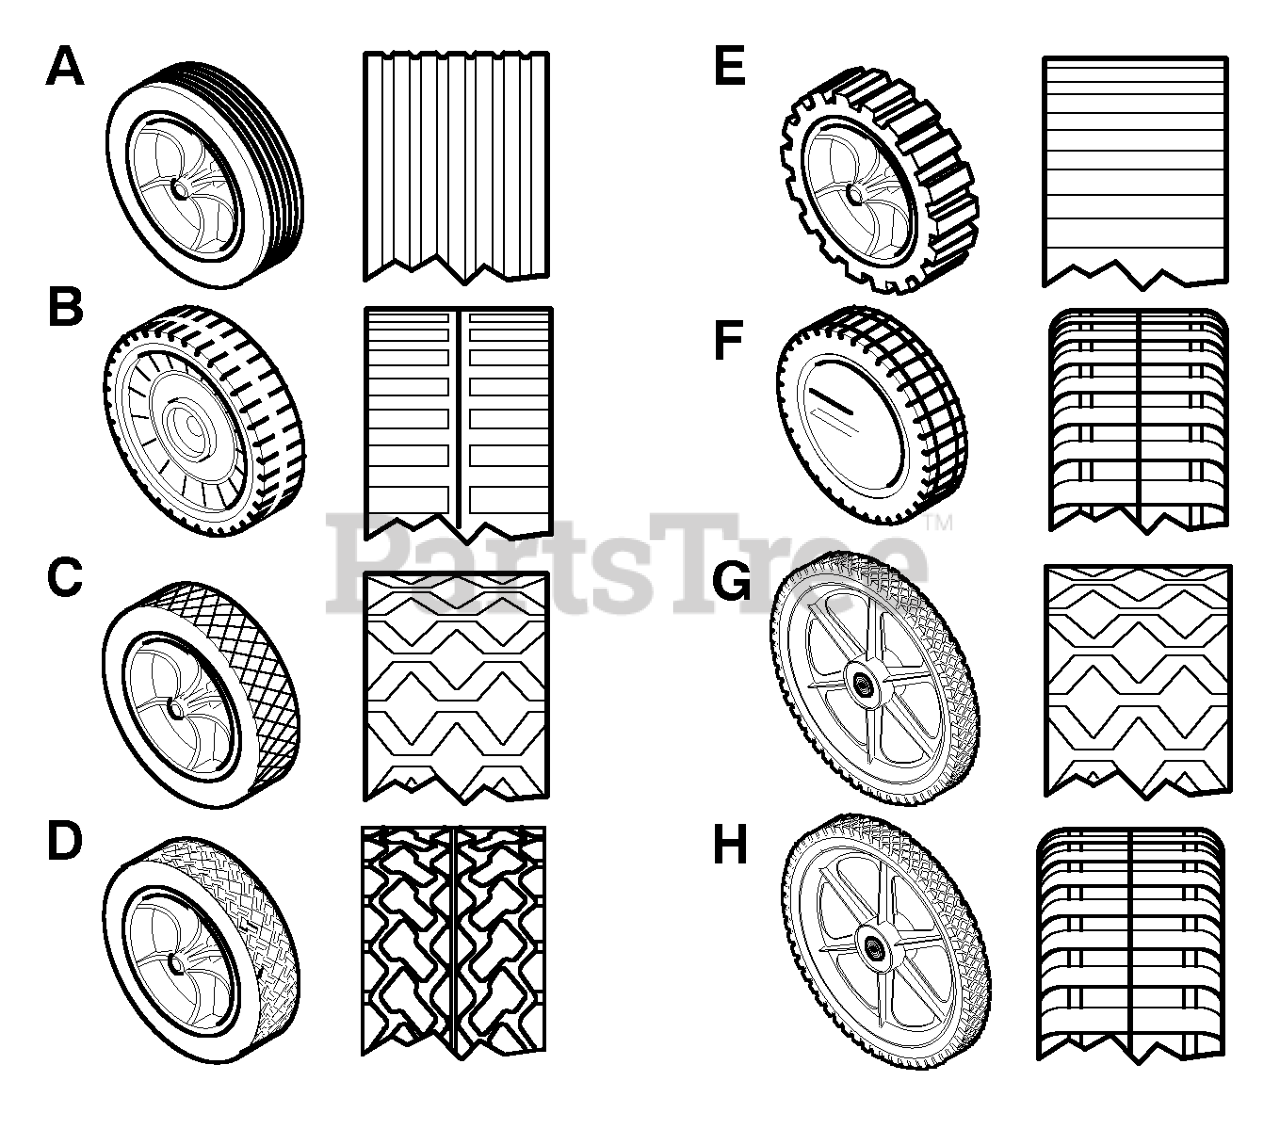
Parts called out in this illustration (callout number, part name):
A	WHEEL & TIRE ASSEMBLY, Light Gray, 8"
A	8-inch Plastic, Dark Gray
A	8-inch Metal, White
B	7-inch Plastic, White
B	7-inch Plastic, Light Gray
B	7-inch Plastic, Dark Gray
C	6-inch Plastic, White
C	7-inch Plastic, White
C	7-inch Plastic, Light Gray
C	7-inch Plastic, Dark Gray
C	8-inch Plastic, White
C	8-inch Plastic, Light Gray
C	8-inch Plastic, Dark Gray
C	8-inch Metal, White
D	7-inch Plastic, White
D	WHEEL & TIRE ASSEMBLY, White, 8"
D	8-inch Plastic, Light Gray
D	8-inch Plastic, Dark Gray
E	WHEEL & TIRE ASSEMBLY, White, 8"
E	8-inch Plastic, Dark Gray
E	8-inch Metal, White
F	WHEEL & TIRE ASSEMBLY, White, 8"
F	8-inch Plastic, Light Gray
F	8-inch Plastic, Dark Gray
F	8-inch Ball Bearing, Light Gray
F	8-inch Ball Bearing, Dark Gray
G	14-inch, White
G	14-inch, Light Gray
G	14-inch, Dark Gray
G	WHEEL & TIRE ASSEMBLY, White, 14"
G	14-in, Ball Bearing, Light Gray
G	14-in, Ball Bearing, Dark Gray
H	14-inch, White
H	14-inch, Light Gray
H	14-inch, Dark Gray
H	WHEEL & TIRE ASSEMBLY, Ball Bearing, 14"
H	14-in, Ball Bearing, Light Gray
H	14-in, Ball Bearing, Dark Gray
